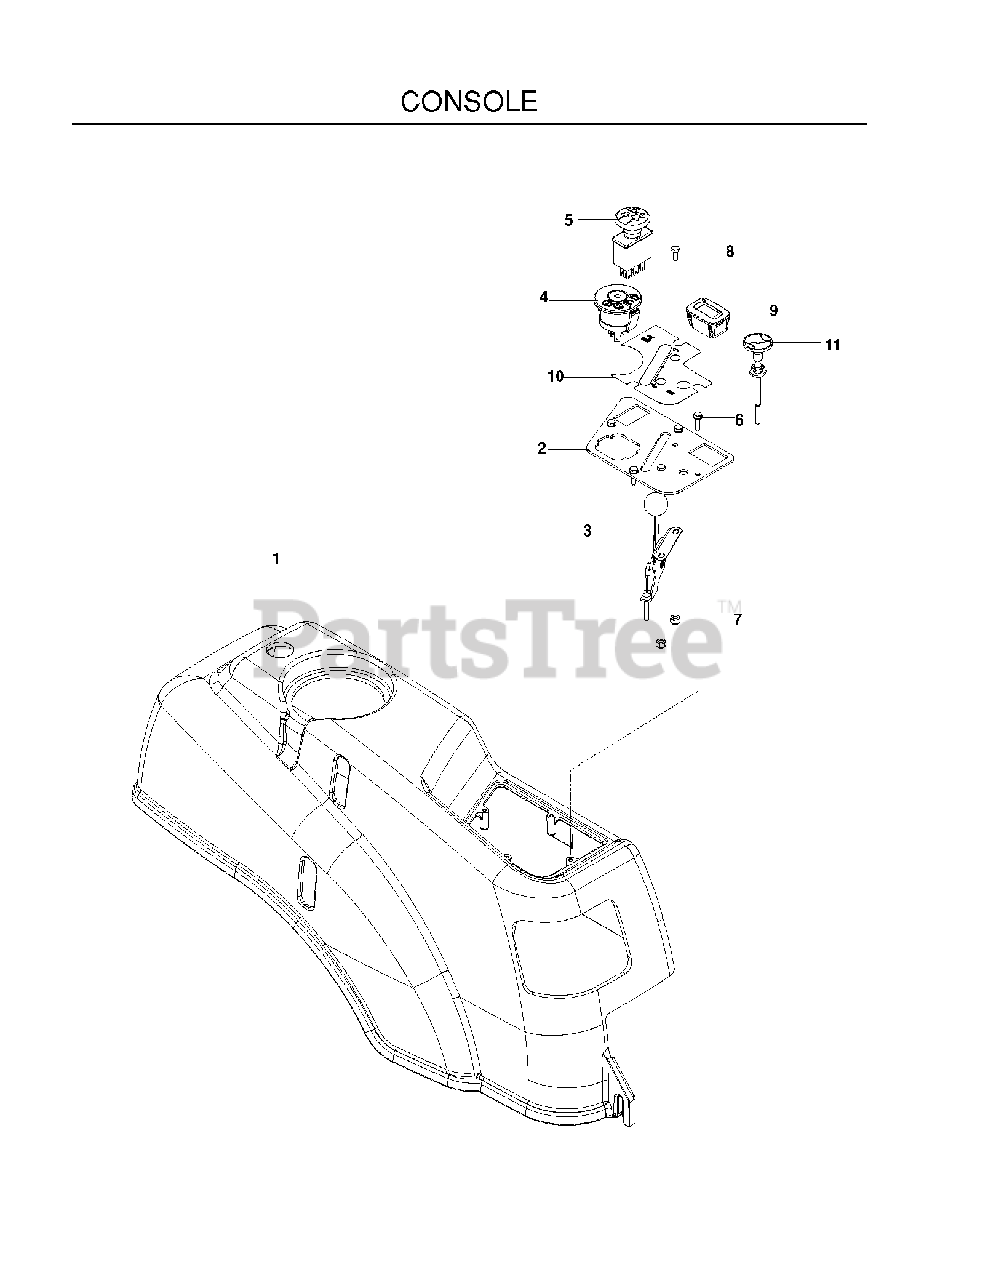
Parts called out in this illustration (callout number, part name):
1	FENDER, RT, BLK
2	CONSOLE.PLATE.BLACK
3	THROTTLE CABLE
4	IGNITION SWITCH
5	SWITCH, BLADE
6	HCS #10-24 X 1/2
7	NUT 10-24 NYLOC
8	SCR #10-12X3/4 HEX WAS HD ZD
9	HOUR METER
10	DECAL, CONTROL PANEL
11	CHOKE CABLE
